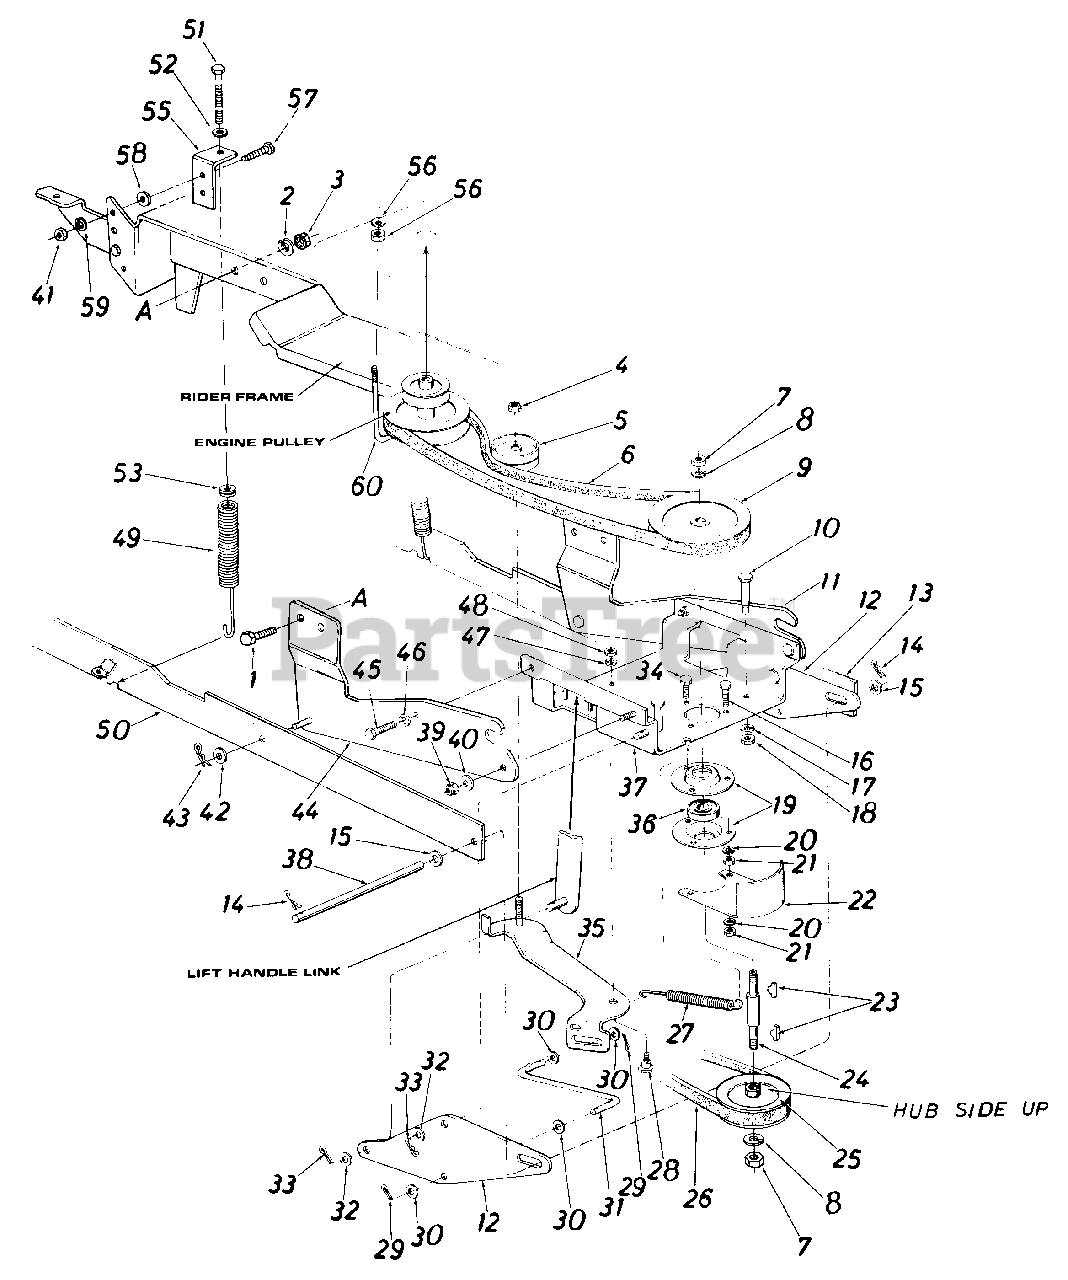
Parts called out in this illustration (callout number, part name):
1	Hex Scr. 1/4-28 x .75" Lg. Grade 5
2	L-Wash. 1/4" Scr.*
3	Hex Nut 1/4-28 Thd.*
4	Hex Ins. Jam Nut 3/8-24 Thd.
5	Flat Idler 3.25" O.D.
6	"V"-Belt 1/2 x 49" Lg.
7	Hex Jam Nut 5/8-11 Thd.
8	L-Wash. 5/8" I.D.*
9	6.50" O.D. x 5/8 Pulley
10	Shoulder Screw
11	Channel Supporting Brk't.-R.H.
12	Linkage Brk't.
13	Linkage Arm Ass'y. R.H.
14	Intern. Cotter Pin .500" Dia.*
15	Fl.-Wash.
16	Hex Scr. 5/16-18 x 1.25"
17	L.-Wash. 3/8" Scr.*
18	Hex Nut 3/8-16 Thd.*
19	Bearing Housing
20	L.-Wash. 5/16" Scr.*
21	Hex Nut 5/16-18 Thd.*
24	Pulley Spindle
25	4.00 O.D. x 5/8 Pulley
26	"V"-Belt 1/2 x 85.2" Lg.
27	Extension Spring
28	ShouIder Screw
29	Cotter Pin 3/32" Dia. x 1 .00*
30	Fl-Wash.
31	Control Rod
32	Fl-Wash.
33	Inter. Cotter Pin .500" Dia.*
34	Hex Sems Scr. 5/16-18 x 1.0" Lg.
35	Clutch Idler Brk't. Ass'y.
36	Ball Bearing
37	Channel Ass'y.
38	Lift Handle Shaft
39	Hex Ins. L-Nut 3/8-16 Thd.
40	Fl.-Wash.
41	Hex Nut 1/4-20 Thd.*
42	Fl.-Wash.
43	Intern. Cotter Pin .500" Dia.*
44	Channel Supporting Brk't.-L.H.
45	Hex Scr. 3/8-16 x 1.00" Lg.*
46	L. Wash. 3/8" Scr.*
47	L.-Wash. 5/16" Scr.*
48	Hex Nut 5/16-18 Thd.*
49	Helper Spring
50	Linkage Arm Ass'y.-L.H.
51	Hex Scr. 5/16-18 x 2.0" Lg.
52	Fl.-Wash. 5/16" Scr.*
53	Spring Insert
57	Hex Bolt 1/4-20 x .75" Lg.*
58	Fl.-Wash. .264" I.D.
59	L.-Wash. 1/4" I.D.*
60	J-Bolt 5/16-18
